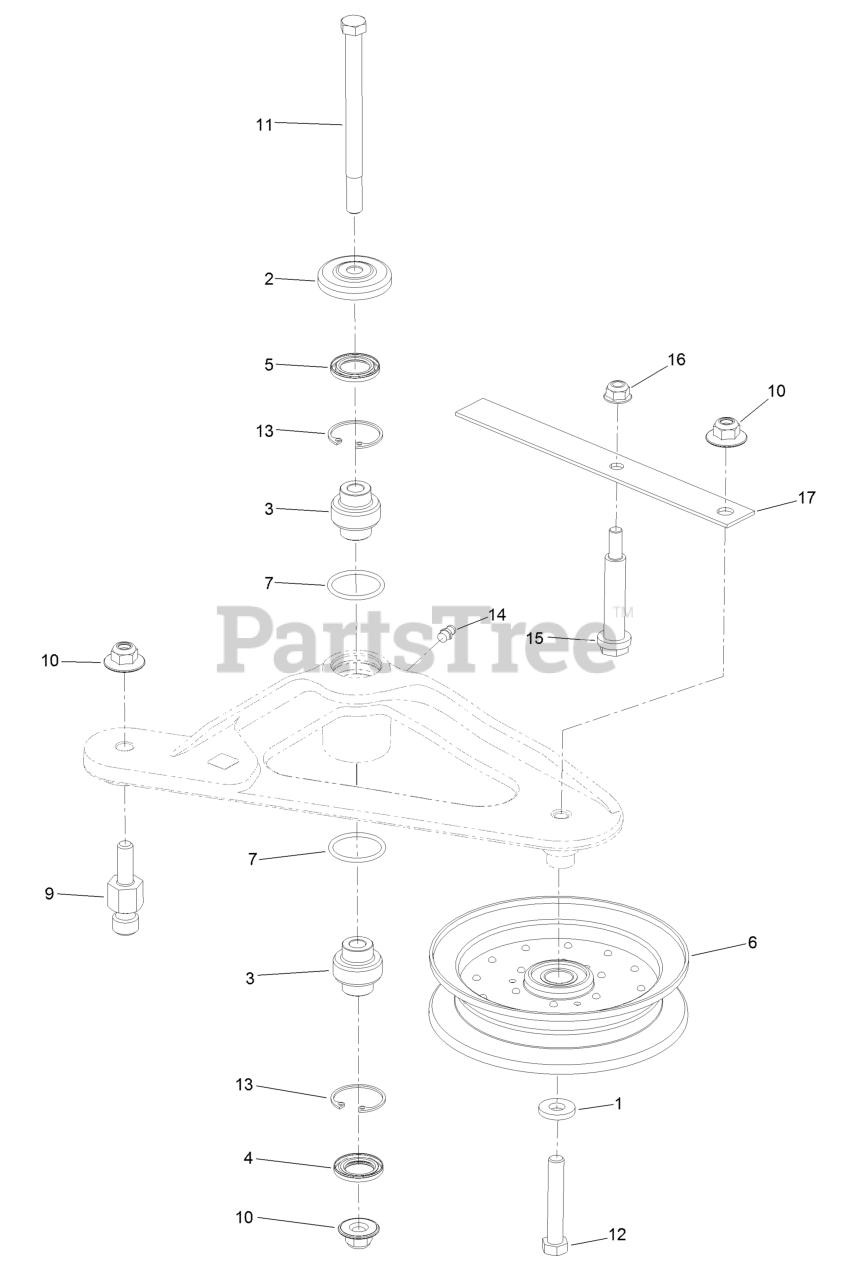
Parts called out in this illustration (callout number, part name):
2	GUARD-TOP
3	BEARING-SPHERICAL
4	SEAL-LIP, DOUBLE
5	SEAL-LIP, SINGLE
9	PIN-SPRING, ANCHOR
10	Nut-Nyloc 3/8-16 Flg
11	SCREW-SHOULDER, HH
12	SCREW-HH
13	RING-SNAP
14	FITTING-GREASE
15	BOLT-SHOULDER
16	NUT-HF, NI
17	SPRING-BELT
